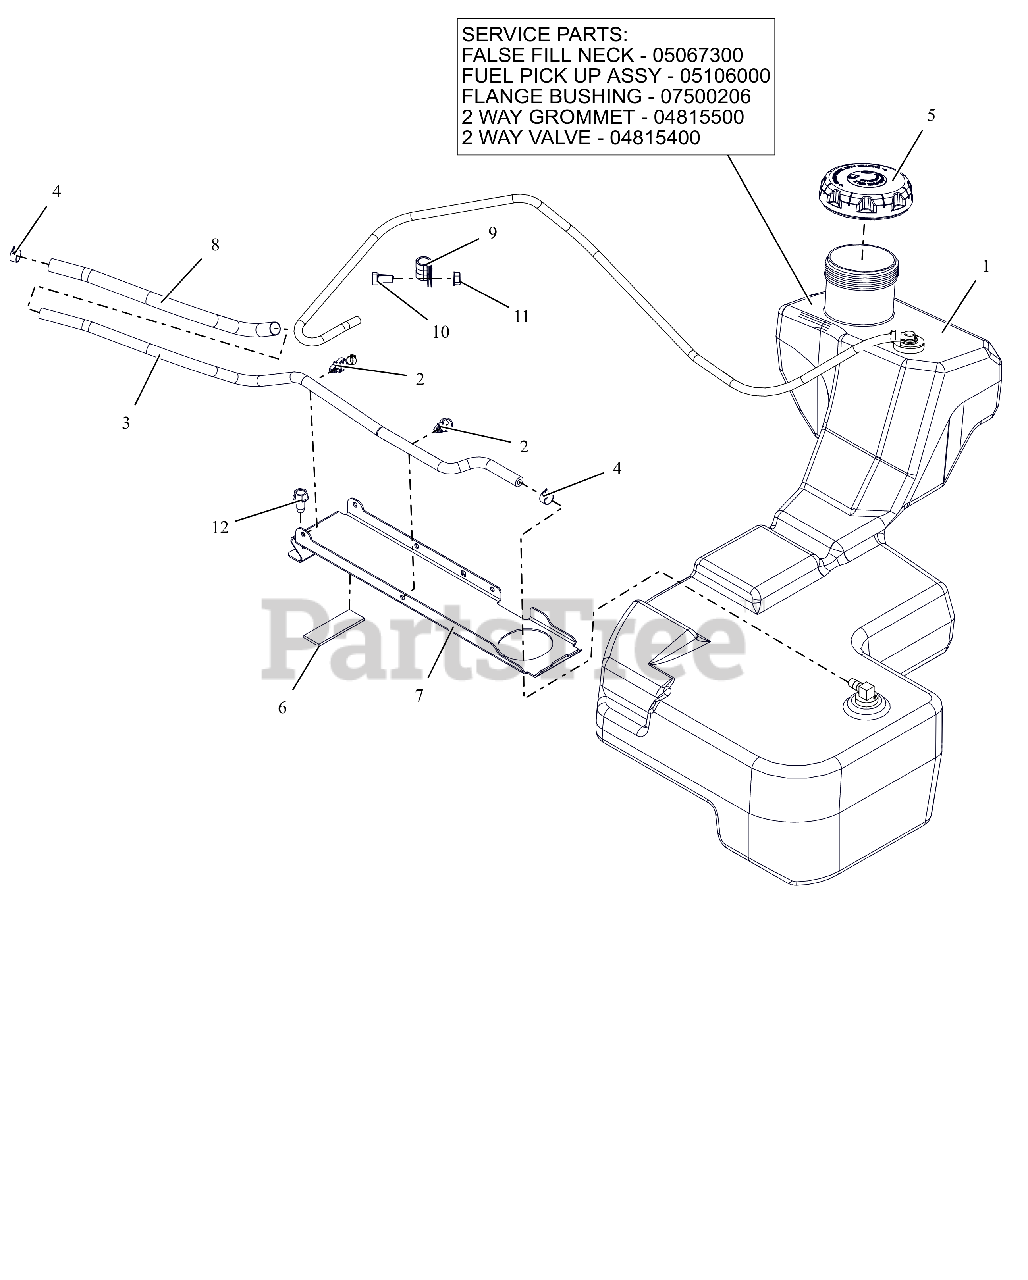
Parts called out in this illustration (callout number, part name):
1	ASSY, FUEL TANK-HD
1	INSERT, FUEL NECK FALSE FILL
1	ASM, HD FUEL PICK-UP
1	BSHG-FLG .375X1.062X.625 NITR
1	GROMMET, 2-WAY
1	VALVE, 2-WAY
2	ROUTING CLIP (1/2" ID)
3	HOSE, .25 LOW-PERM BULK GAS
4	CLAMP, FUEL LINE
5	CAP, FUEL VENTIN AUTOLOCK
6	PAD,RBR 1.0"X3.0" W/ADHESIVE
7	BRKT, FUEL TANK HOLD DOWN
8	SLEEVE, THERMAL 12"
9	CLAMP, CUSHIONED STEEL
10	BLT,HEX .31-18X.75 G5 ZCC
11	NUT,LK-CTR-FLG .31-18 GF ZCC
12	SCR,TAP .375-16X.75 HWH TR ZCC
